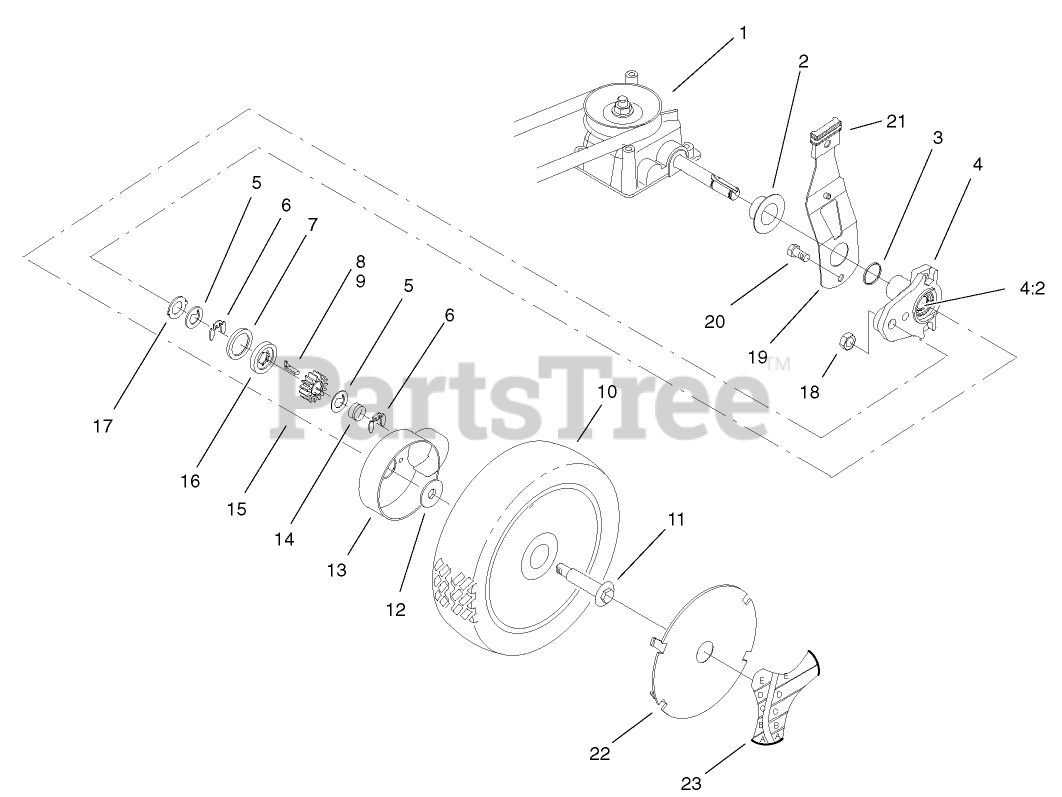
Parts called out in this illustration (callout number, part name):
1	V-BELT
2	CAP-END
3	O-RING
4	PIVOT ARM ASM
5	WASHER-THRUST, KEYED
6	RING-RETAINING,CLIP
7	RING-FRICTION
8	KEY-ROCKING, RH
9	KEY-ROCKING, LH
10	WHEEL ASM
11	BOLT-SHOULDER
12	SPACER-COVER, WHEEL
13	COVER-WHEEL
14	SPRING-COMPRESSION
15	GEAR-PINION
16	WASHER-CLUTCH
17	WASHER-ARM, PIVOT
18	LOCKNUT
19	SPRING ARM ASM
20	SCREW-HWH
21	KNOB-ARM
22	COVER-WHEEL, SMART
23	LABEL-WHEEL, SMART
